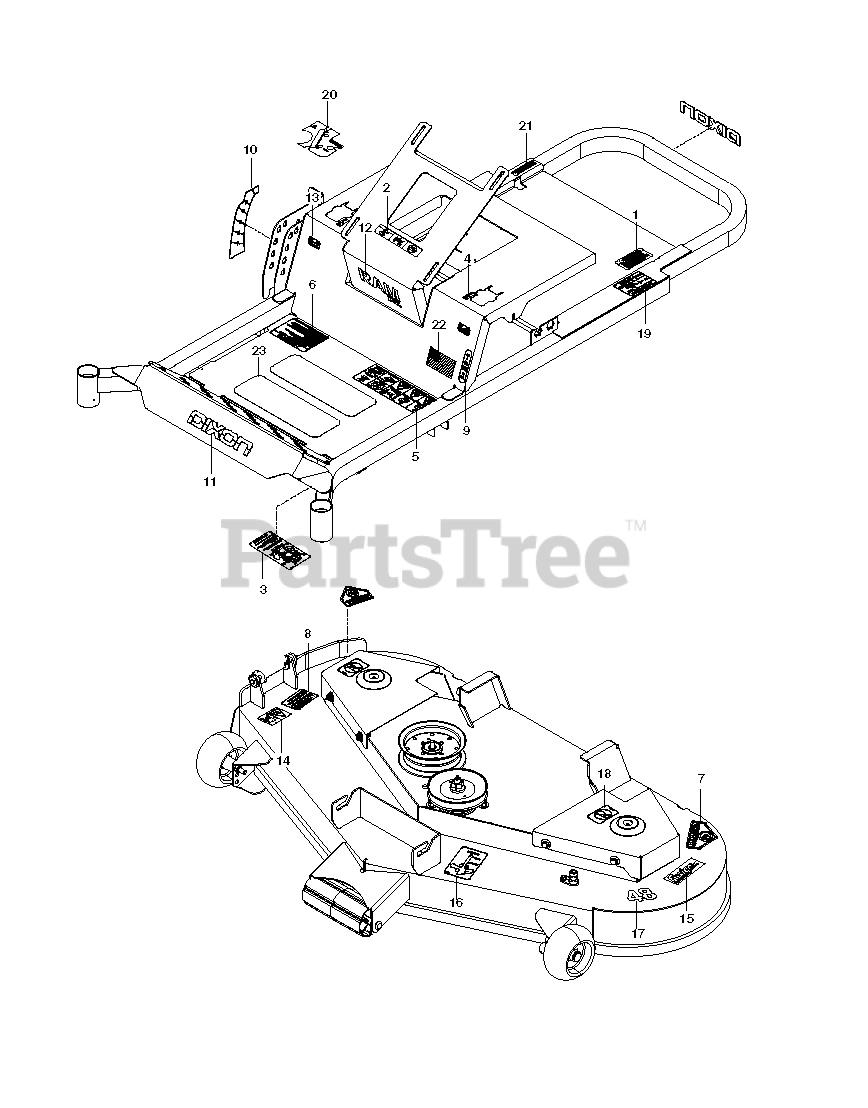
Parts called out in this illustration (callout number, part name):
1	DECAL, PROP. 65
3	DECAL, SERVICE
4	DECAL, MOTION CONTROL
5	DECAL, SAFETY WARNING
6	DECAL, WARNING
7	DECAL, CPSC
8	DECAL, CAUTION
9	DECAL, PARK BRAKE
10	DECAL, HEIGHT
12	DECAL, RAM ZTR, 2008
13	DECAL, TRACKING
14	DECAL, EURO SEVERING
15	DECAL, FUSION
16	DECAL, BELT ROUTING
18	DECAL, NO STEP
19	DECAL, DO NOT MOUNT
20	DECAL, CONTROLS PANEL, DIX
21	DECAL, WARNING SPARK ARRESTOR
22	DECAL, FLAG
23	ANTI-SKID PAD
